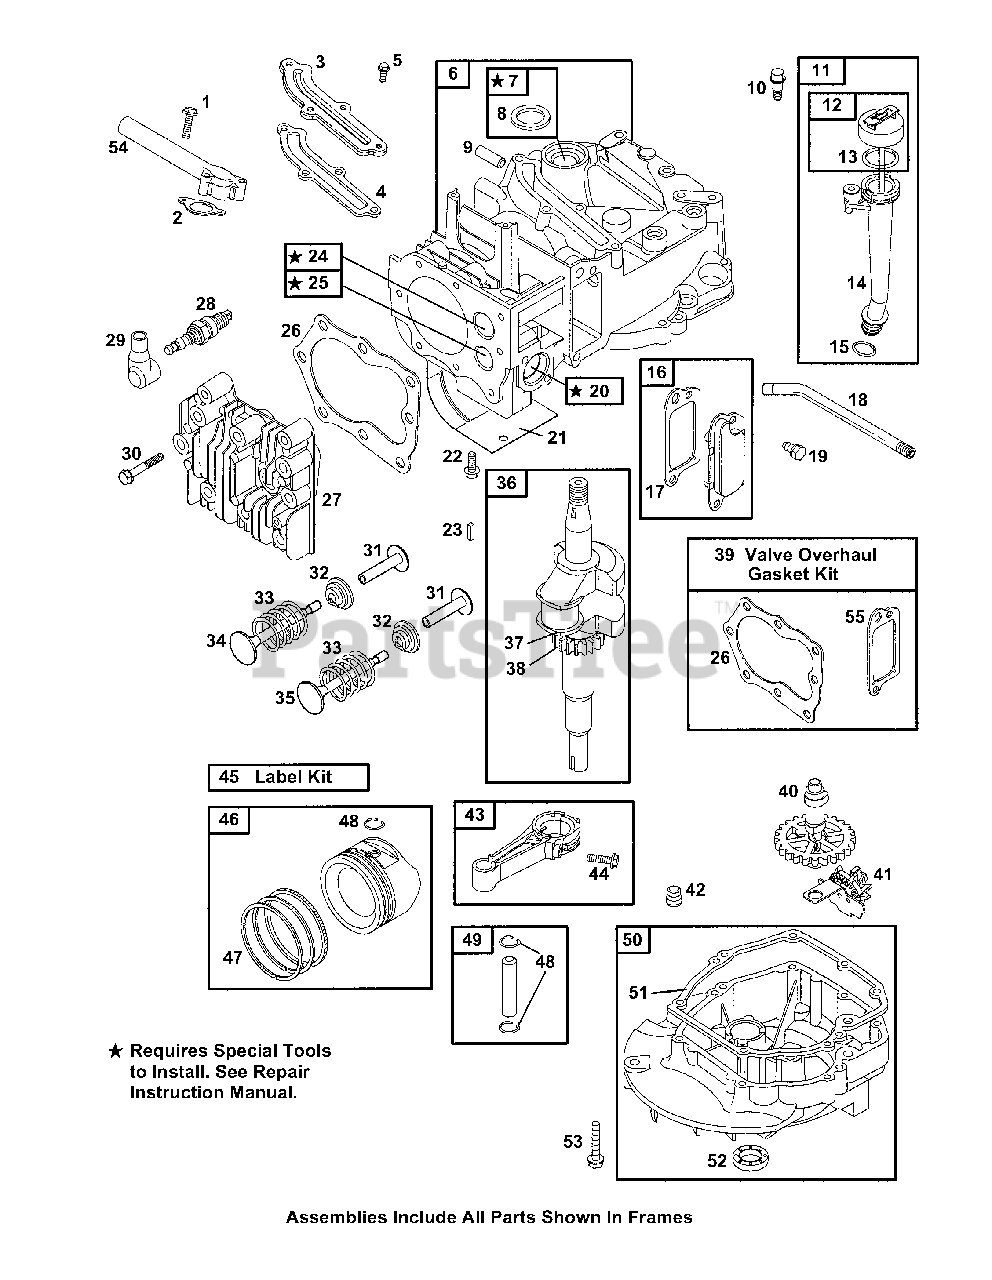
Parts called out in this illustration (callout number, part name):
1	Screw (Intake Manifold)
2	Intake Gasket
3	Breather Passage Cover
4	Breather Passage Gasket
5	Screw (Breather Passage Cover)
6	Cylinder Assembly
7	Bushing/Seal Kit
8	Oil Seal
9	Locating Pin
10	Screw (Dipstick Tube)
11	Order Component Part
12	Dipstick
13	Dipstick/Tube Seal
14	Oil Fill Tube
15	Dipstick Tube Seal
16	Breather Assembly
17	Breather Gasket
18	Breather Tube
19	Screw (Breather Assembly)
20	Guide Bushing (Intake Valve)
21	Cylinder Shield
22	Screw (Cylinder Shield)
23	Flywheel Key
24	Valve Seat (Intake)
25	Valve Seat (Exhaust)
26	Cylinder Head Gasket
27	Cylinder Head
28	Spark Plug
29	Sparkplug Boot
30	Screw (Cylinder Head)
31	Valve Tappet
32	Valve Retainer
33	Valve Spring (Intake)
34	Intake Valve
35	Exhaust Valve
36	Crankshaft
37	Timing Key
38	Timing Gear
39	Valve Gasket Set
41	Governor/Oil Slinger
42	Oil Drain Plug
43	Connecting Rod
44	Screw (Connecting Rod)
46	Piston Assembly
47	Ring Set
48	Piston Pin Lock
49	Piston Pin
50	Engine Sump
51	Crankcase Gasket
52	Oil Seal
53	Screw (Engine Sump)
54	Intake Manifold
55	Breather Gasket
